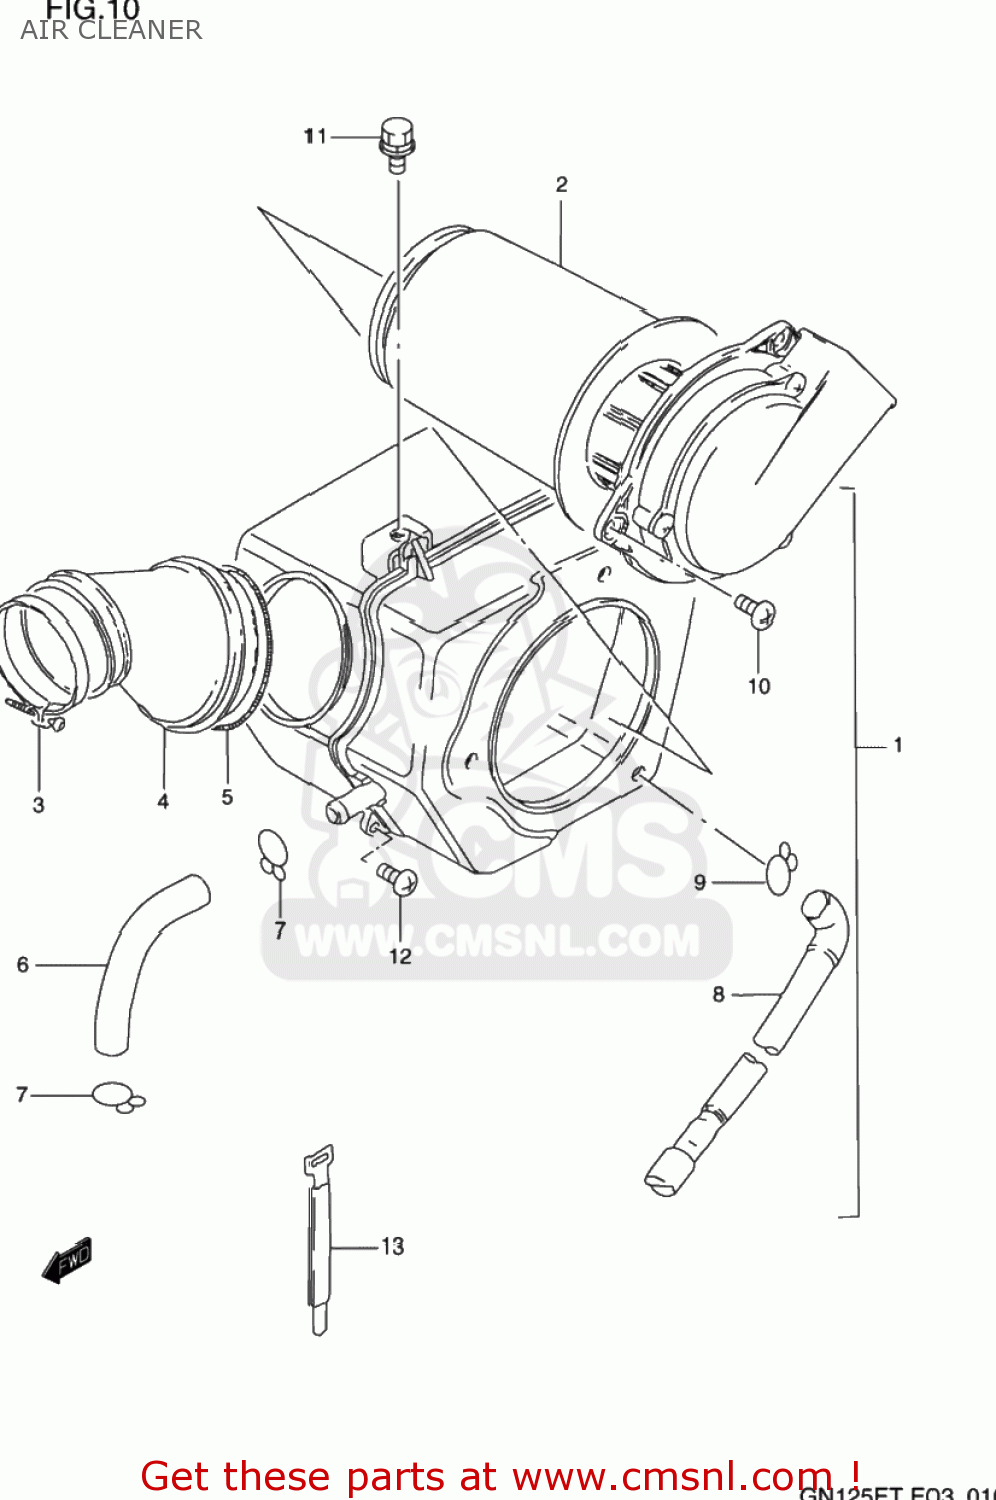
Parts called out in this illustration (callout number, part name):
1	CLEANER ASSY,AIR
2	FILTER
3	CLAMP
4	TUBE,OUTLET
5	CLAMP,AIR CLEANER SIDE
6	TUBE,BREATHER
7	CLIP
8	DRAIN TUBE
9	CLIP
10	SCREW
11	BOLT
12	SCREW
13	CLAMP L:110
